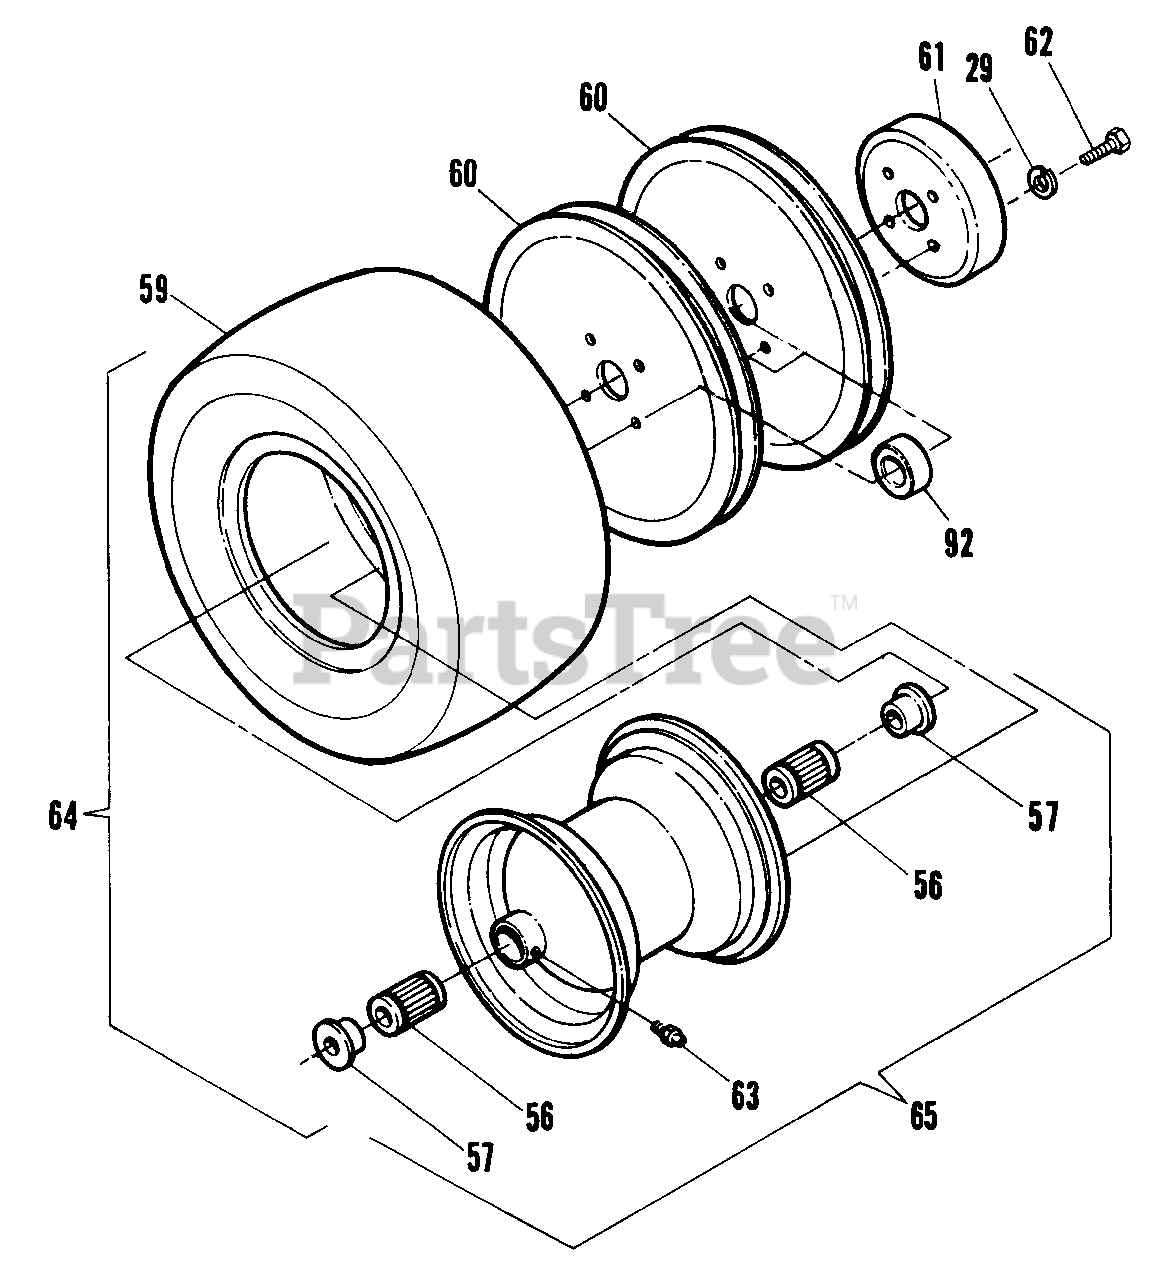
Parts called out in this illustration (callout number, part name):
29	WASHER, Lock 3/8
56	BEARING, Roller
57	BUSHING, Flange
59	TIRE, 4 Ply Turfsaver
60	PULLEY, Traction
61	HUB, Brake
62	SCREW, Hex Head Cap 3/8" - 24 x 5/8
63	ZERK, 1/4 - 28
64	WHEEL ASS'Y (w/out Pulleys)
65	RIM w/Flange Ass'y
92	WASHER, 1/4 "D"
